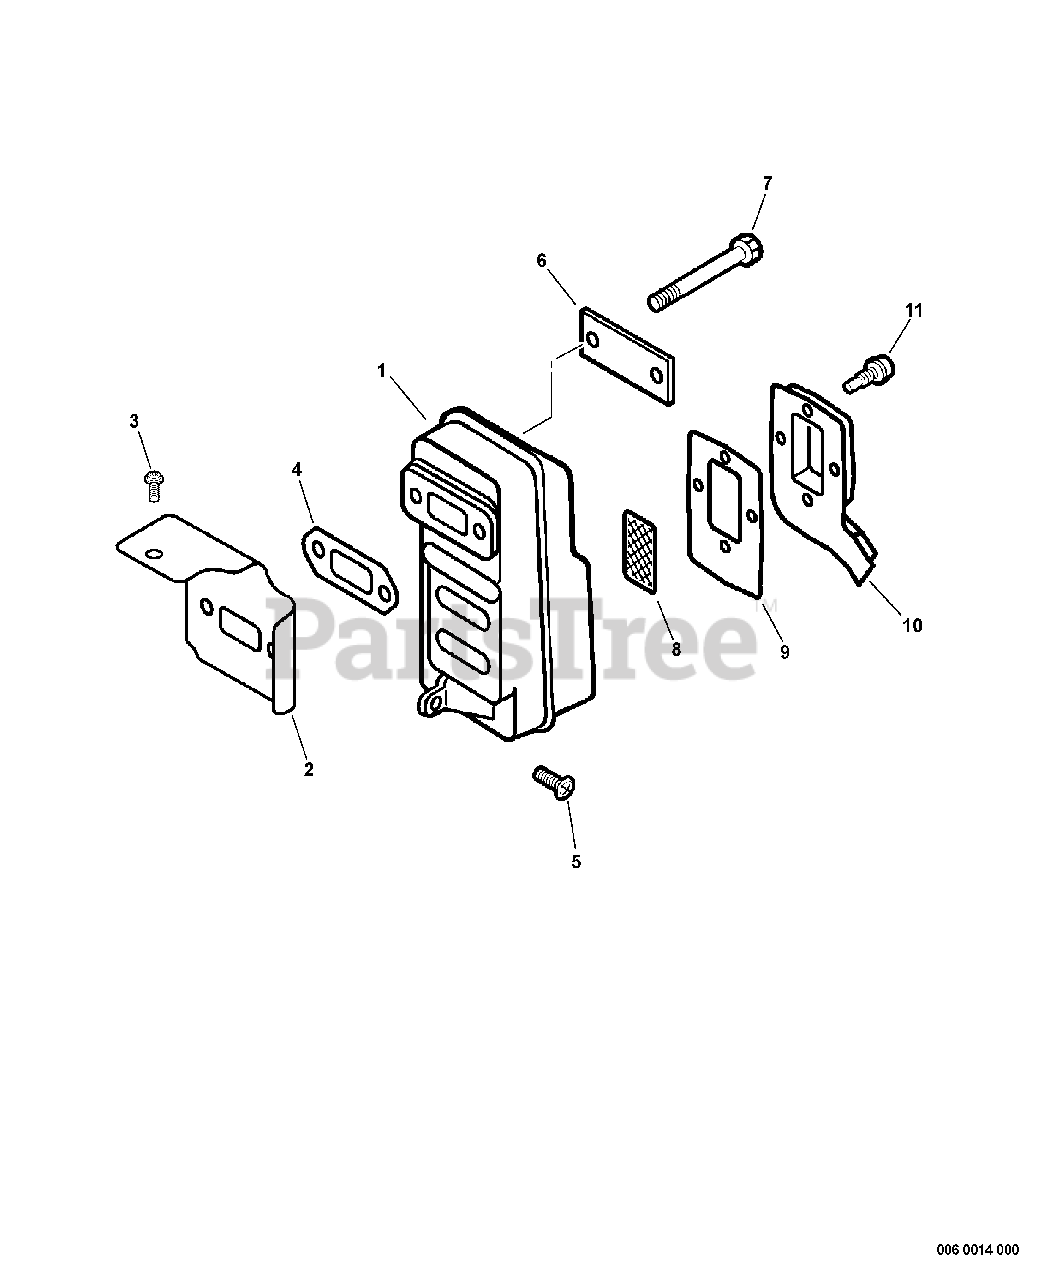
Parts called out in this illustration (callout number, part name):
1	MUFFLER
2	COVER, CYLINDER
3	SCREW 5×10
4	GASKET, EXHAUST
5	BOLT 5×20
6	PLATE, EYE
7	BOLT
8	SCREEN, SPARK ARRESTER
9	GASKET, EXHAUST
10	GUIDE, EXHAUST
11	SCREW
